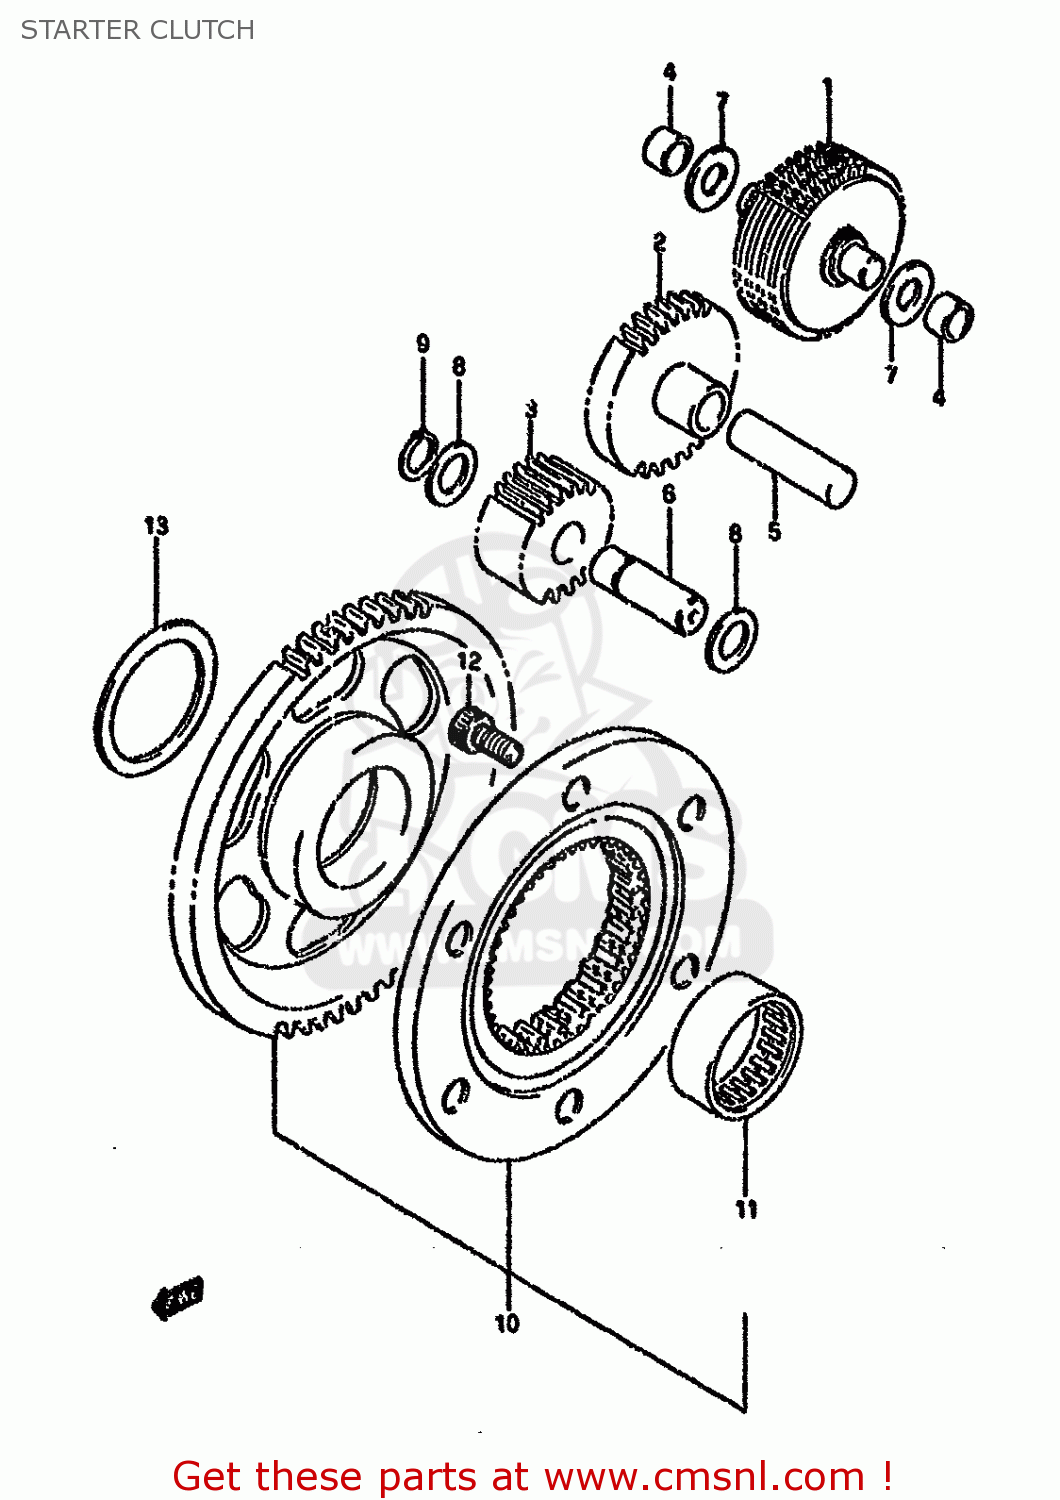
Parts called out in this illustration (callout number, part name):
1	LIMITER ASSEMBLY,STARTER IDLER GEAR
2	GEAR,STARTER IDLE NO.2(NT:27)
3	GEAR,STARTER IDLE NO.3
4	BUSH,LIMITER GEAR SHAFT
5	PIN
6	SHAFT,STARTER IDLE GEAR
7	WASHER
8	SHIM
9	CIRCLIP,12 MM
10	CLUTCH SET,STARTER
11	BEARING(31X39X17.8)
12	BOLT
13	SHIM
